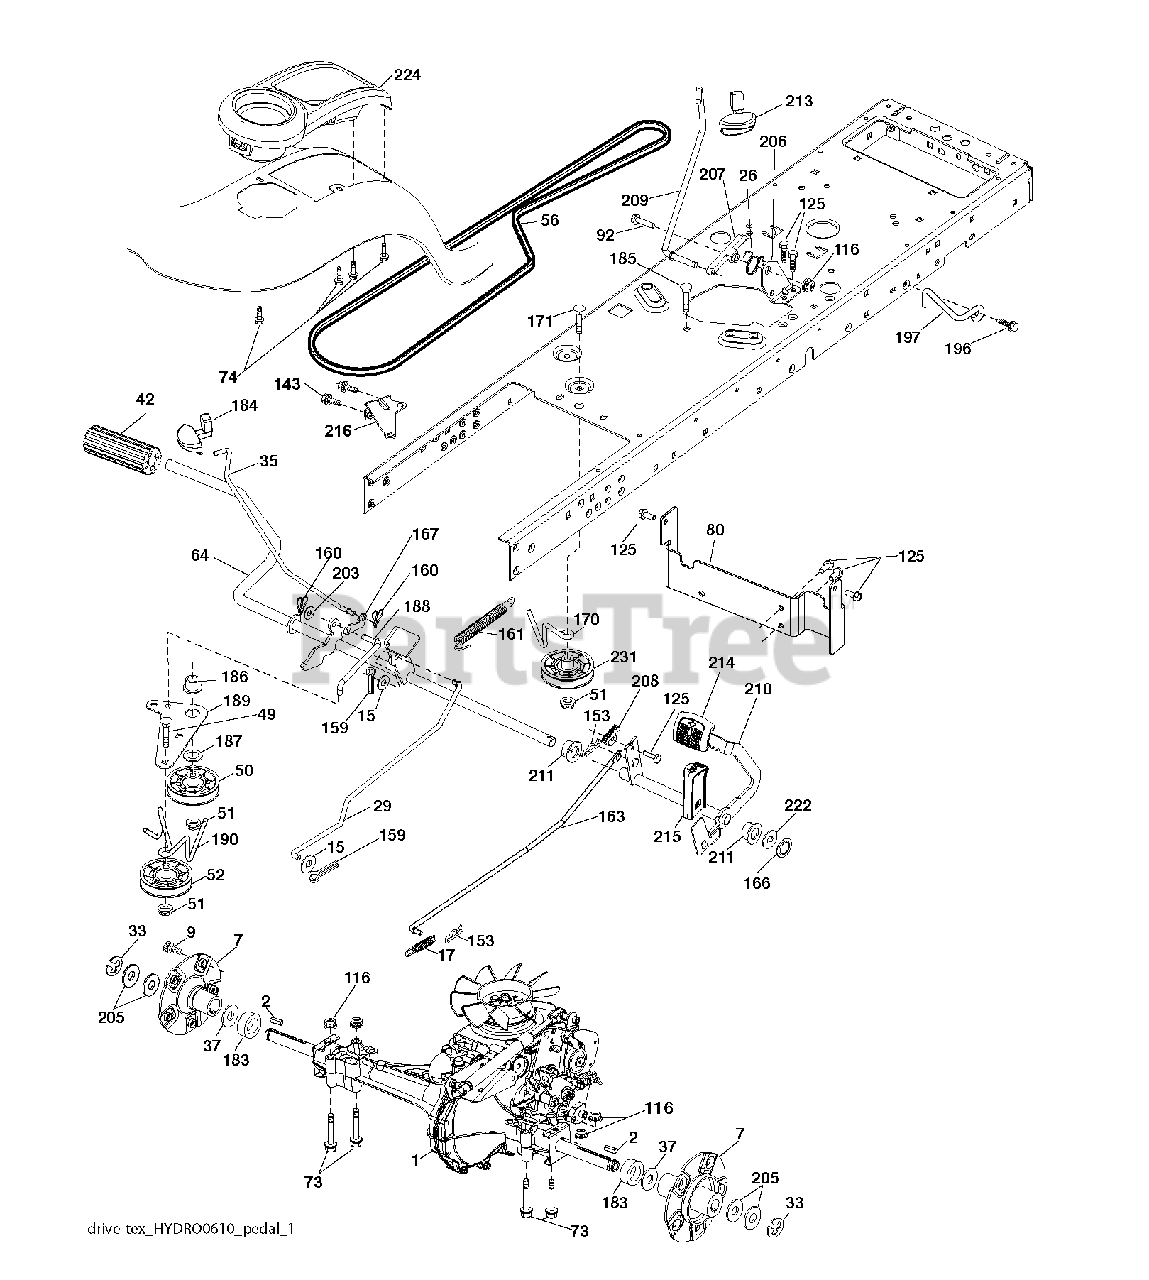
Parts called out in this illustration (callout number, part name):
2	KEY.SQUARE.187X2.500
7	HUB.ASM.WHEEL.REAR.22"
9	HUB BOLT
17	SPRING.BRAKE.HG3000/3500
26	SPRING.RETURN.CRUISE
29	ROD.BRAKE.0610.PEDAL.CONTROL
33	E-RING LT
35	ROD.BRKAE.PARKING.STEALTH
42	PEDAL COVER T
49	BOLT
50	IDLER.FLAT.910.OFFSET
51	NUT LOCK FLG 3/8-16 UNC
52	IDLER.V-GROOVE.910.OFFSET
64	SHAFT.ASM.PEDAL.BRK.CNTR
73	BOLT HEX 5/16-18 GR 5
74	SCREW.HI-LO.CONSOLE
80	BRKT.STRP.TRQ.LT.HYD.C
92	BOLT
116	NUT LOCK HEX FLANGE 5/16-18
125	SCREW
143	SCREW LT
153	RETAINER M
159	COTTER PIN
160	RETAINER CLIP
161	SPRING.RETURN.CLUTCH.2006
163	ROD.PEDAL.CONTROL.0510
166	NUT.PUSH.625.2006
167	LATCH.BRAKE.SPRING
170	KEEPER.V-IDLER.CENTER.
183	SPACER.SPLIT.800X.350
184	HANDLE.PRKG.BRAKE.STLTH.TX.RED
185	BOLT
186	SPACER.RETAINER
187	WASHER 12/32X2X10GA
188	LINK.CLUTCH.GROUND.DRIVE
189	BELLCRANK.GROUND.DRIVE.TEX.
190	KEEPER.BELLCRANK.DRIVE
196	SCREW 3/8-16X1
197	BRKT.ANIT-ROTATION.CLU
203	WASHER
206	BRKT.MOUNT.LATCH.CRUIS
207	LATCH.CONTROL.CRUISE
208	GEAR.SECTOR.CONTROL.CR
209	ROD.CONTROL.CRUISE.STEALTH.TEX
210	ROCKER.ASM.PEDAL.CONTR
211	BEARING.NYLON
213	KNOB.CONTROL.CRUISE
214	PEDAL.FORWARD.TEX.GT.4
215	PEDAL.REVERSE.TEX.GT.4
216	BRACKET.PULLEY.IDLER.W/TEX
221	RETAINER.SPRING.CLIP.H
222	WASHER 21/32 X 1-1/4 X 10 GA.
224	CONSOLE.TOOLBOX.PCH.ERGO.BLACK
231	IDLER.V-GROOVE.1.688.OFFSET
